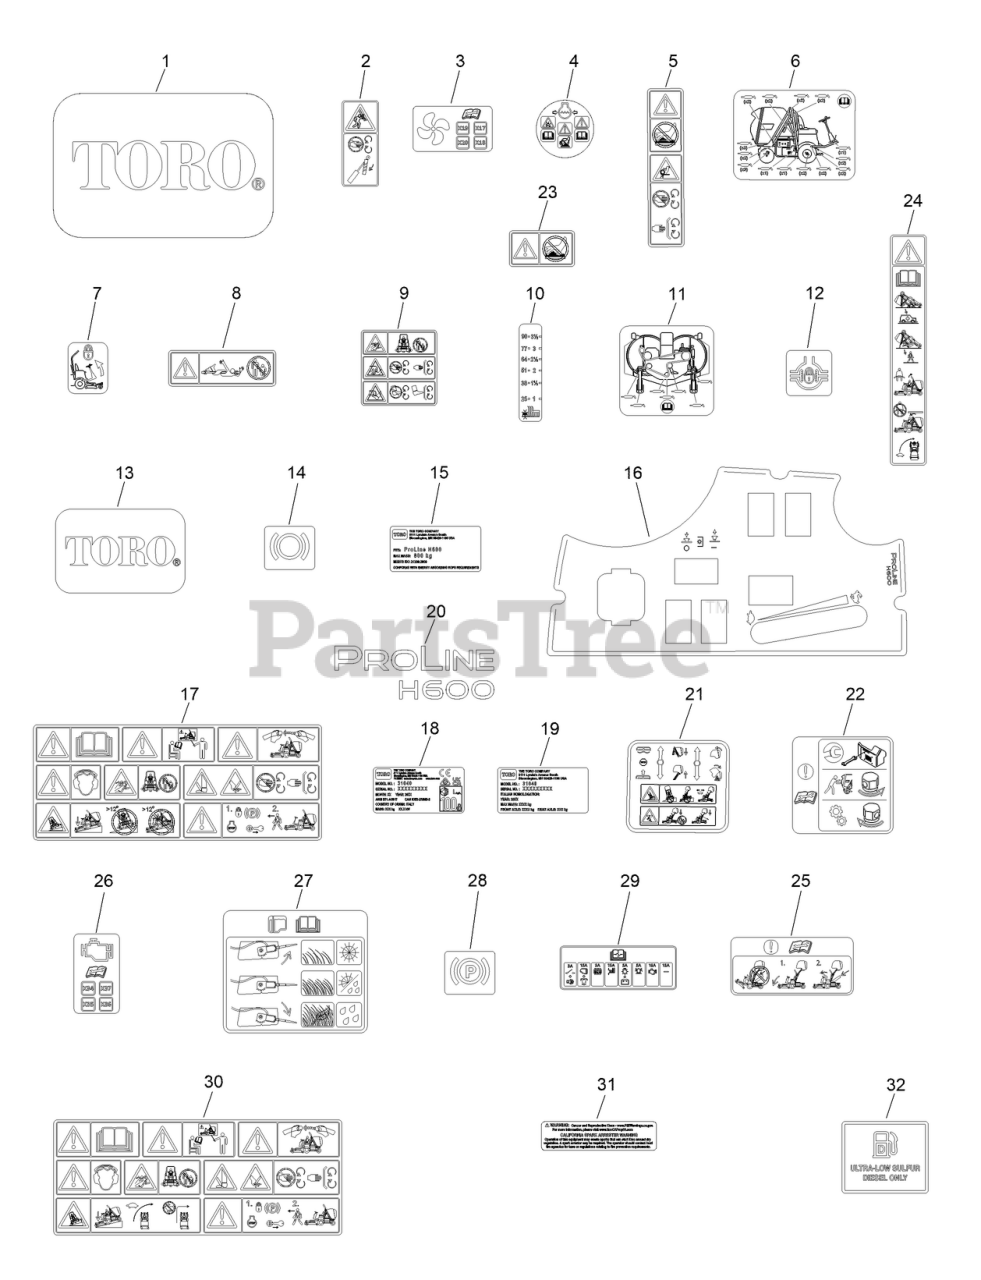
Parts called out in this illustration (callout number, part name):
2	DECAL-WARNING ARM
3	DECAL-RELAY FAN
4	DECAL-DANGER
5	DECAL-WARNING ENGINE
6	DECAL-SERVICE
7	DECAL-FOOTPLATE TILT
8	DECAL-CARDAN JOINT
9	DECAL-WARNING DECK
10	DECAL-HOC
11	DECAL-SERVICE
12	DECAL-DIFFERENTIAL LOCK
13	DECAL-TORO LOGO
14	DECAL-BRAKE
15	DECAL-ROPS COMPLIANCE
16	DECAL-CONTROL PANEL
17	DECAL-WARNING
18	DECAL-MODEL/SERIAL
19	DECAL-HOMOLOGATION
20	DECAL-PROLINE H600
21	DECAL-CONTROLS SAFETY
22	DECAL-HYDROSTATIC PUMP BYPASS
23	DECAL-HOT SURFACE
24	DECAL-ROPS WARNING
25	DECAL-ATTENTION, DECK SERVICE
26	DECAL-ENGINE RELAY
27	DECAL-HOPPER SENSOR
28	DECAL-PARKING BRAKE
29	DECAL-FUSE
30	DECAL-WARNING
31	DECAL-ARRESTOR, SPARK
32	DECAL-DIESEL, ULTRA-LOW
